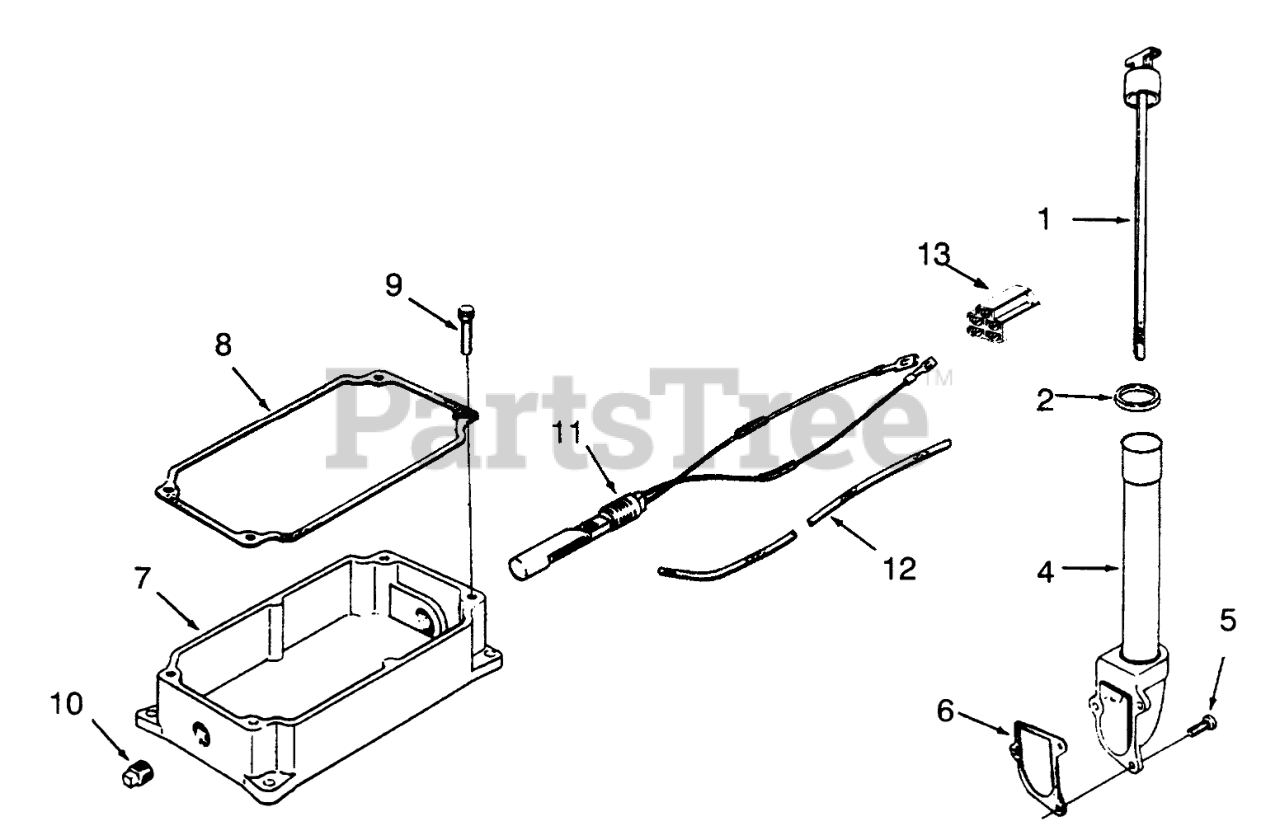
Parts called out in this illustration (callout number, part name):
1	Dipstick
2	0-Ring
4	Adapter-Oil Fill
5	Screw
6	Gasket
7	Oil Pan
8	Gasket
9	Screw
11	Kit-Float Switch (Incl. Ref.#12 & Decal)
12	Sleeve
13	Connector
